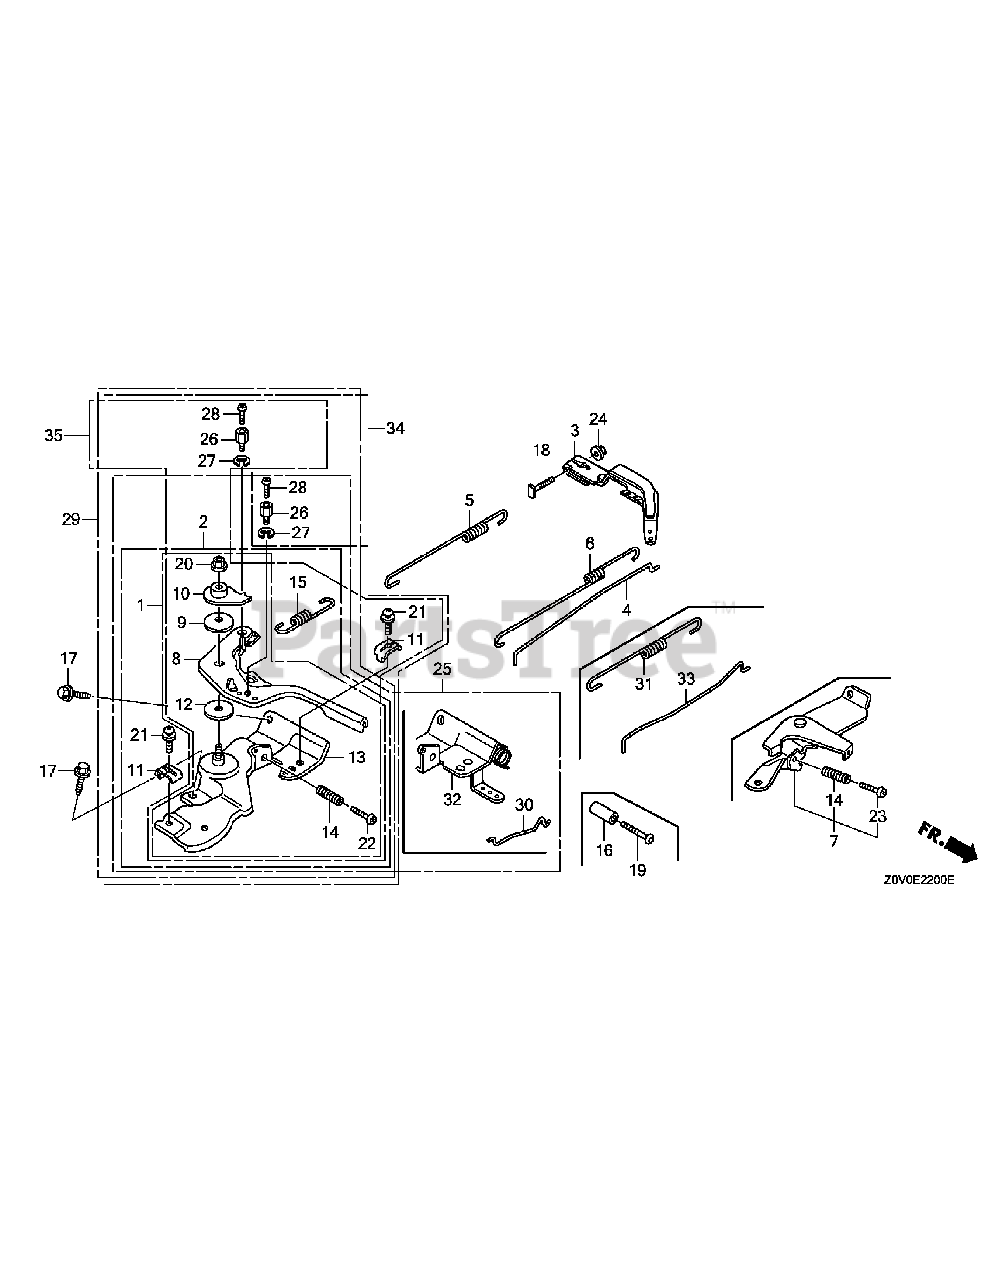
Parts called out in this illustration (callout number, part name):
1	Control Assy
2	Control Assy.(Remote)
3	Arm, Governor
4	Rod, Governor
5	Spring, Governor
6	Spring, Throttle Return
7	Control Assy
8	Lever, Control
9	Spring, Lever
10	Washer, Control Lever
11	Holder, Cable
12	Spacer, Control Lever
13	Base Comp., Control
14	Spring, Control Adjusting
15	Spring, Cable Return
16	Collar, Stopper
17	Bolt, Flange, 6X12(Ct200)
18	Bolt, Governor Arm
19	Screw, Recessed, 5X25
20	Nut, Self-Lock, 6Mm
21	Screw, Pan, 5X16
22	Screw, Pan, 5X25
23	Screw, Pan, 5X35
24	Nut, Flange, 6Mm
25	Control Assy.(
26	Holder, Wire
27	Circlip, 5Mm
28	Screw, Pan, 4X6
29	Control Assy.(Norton)
30	Rod, Control
31	Spring, Throttle Return
32	Base Comp., Control
33	Rod, Throttle
34	Control Assy.(Remote Intl-S)
35	Control Assy.(Remote Intl-S)
